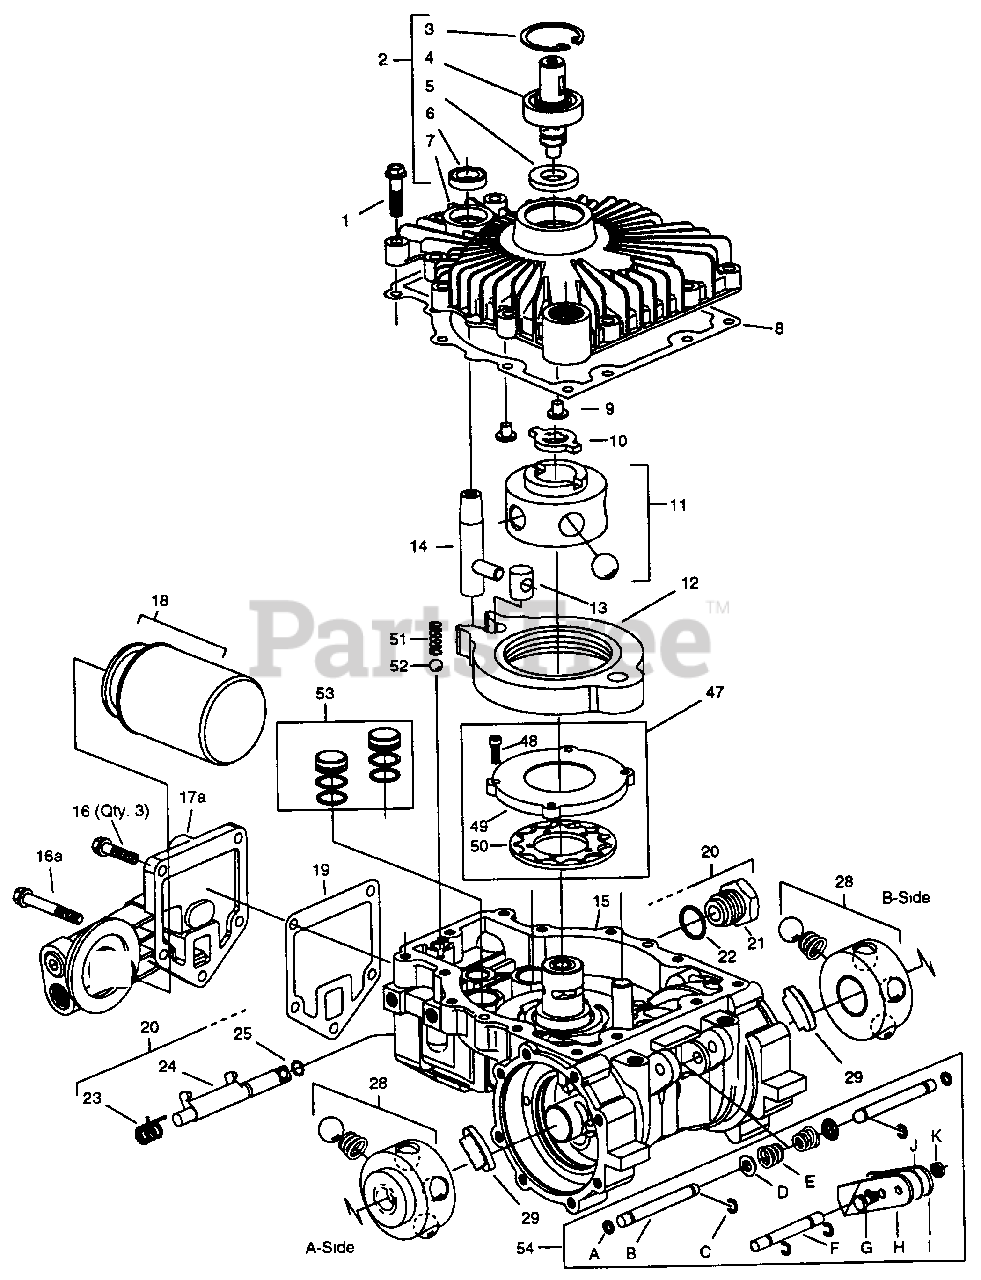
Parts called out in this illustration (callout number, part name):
1	SCREW, 1/4-20 SELF TAP.(13)
2	ASM, COVER(SA)
3	RING, RETAINING INTERNAL
4	SHAFT, INPUT(SA)
5	SEAL, INPUT SHAFT
6	SEAL, CONTROL SHAFT
7	COVER
8	GASKET, COVER
9	BUTTON(2)
10	DRIVE
11	PUMP, ROTOR-BALL-PIN(SA)
12	CAM RING(SA)
13	INSERT
14	SHAFT, CONTROL EXT. THRD.
14A	SHAFT, CONTROL
15	HOUSING(SA)
16	SCREW, 1/4-20 HEX FLANGE(AR)
16A	SCREW, 1/4-20 HEX FLANGE
16B	SCREW, 1/4-20 HEX FLANGE(2)
17A	BASE, FILTER "U"
18	FILTER, OIL
19	GASKET, FILTER BASE
20	O-RING, DUMP VALVE NUT
20A	DUMP VALVE PARTS
21	NUT, DUMP VALVE
22	O-RING, DUMP VALVE NUT
23	SPRING, DUMP VALVE
24	BRACKET, DUMP VALVE
25	O-RING, DUMP VALVE BRACKET
26	SCREW, 5/16 HEX FLANGE(16)
27	GASKET, AXLE HOUSING(2)
28	MOTOR, ROTOR-BALL(2)
29	PAD, FRICTION(SA)(2)
30	PLATE, REACTION(2)
31	PLATE, BACKUP(2)
35	15T CARRIER, PRIMARY(SA)(2)
37	21T PLANET GEAR(SA) SECOND(STEEL)(6)
38	CARRIER, SECONDARY(SA)(2)
39	HOUSING, AXLE(SA) A-SIDE
39A	HOUSING, AXLE(SA) B-SIDE
40	HOUSING, AXLE(2)
41	RING, RETAINING EXTERNAL(4)
42	WASHER, THRUST(4)
43	RING, RETAINING INTERNAL(2)
44	BEARING, AXLE SHAFT(2)
45	SEAL, AXLE SHAFT(2)
46	SHAFT, AXLE A-SIDE
46	SHAFT, AXLE B-SIDE
47	PUMP, CHARGE
48	SCREW, CAP, SOCKET
49	PLATE, PUMP(CLASS II)
50	GEROTOR(CLASS II)
51	SPRING, RELIED VALVE
52	BALL, GRADE 200
53	PISTON, DAMPENING
54	BRAKE LEVER PARTS
55	.625 STR. FITTING/O-RING
A	QUAD SEAL(2)
B	ROD, PUSH(2)
C	E-RING(4)
D	SPRING BASE(SA)(2)
E	SPRING, CONICAL(2)
F	SHAFT, BRAKE
G	SCREW, CAP, HEX
H	LEVER, BRAKE RH
I	LEVER, BRAKE LH
J	SHIM(AR)
K	NUT, HEX, LOCK
